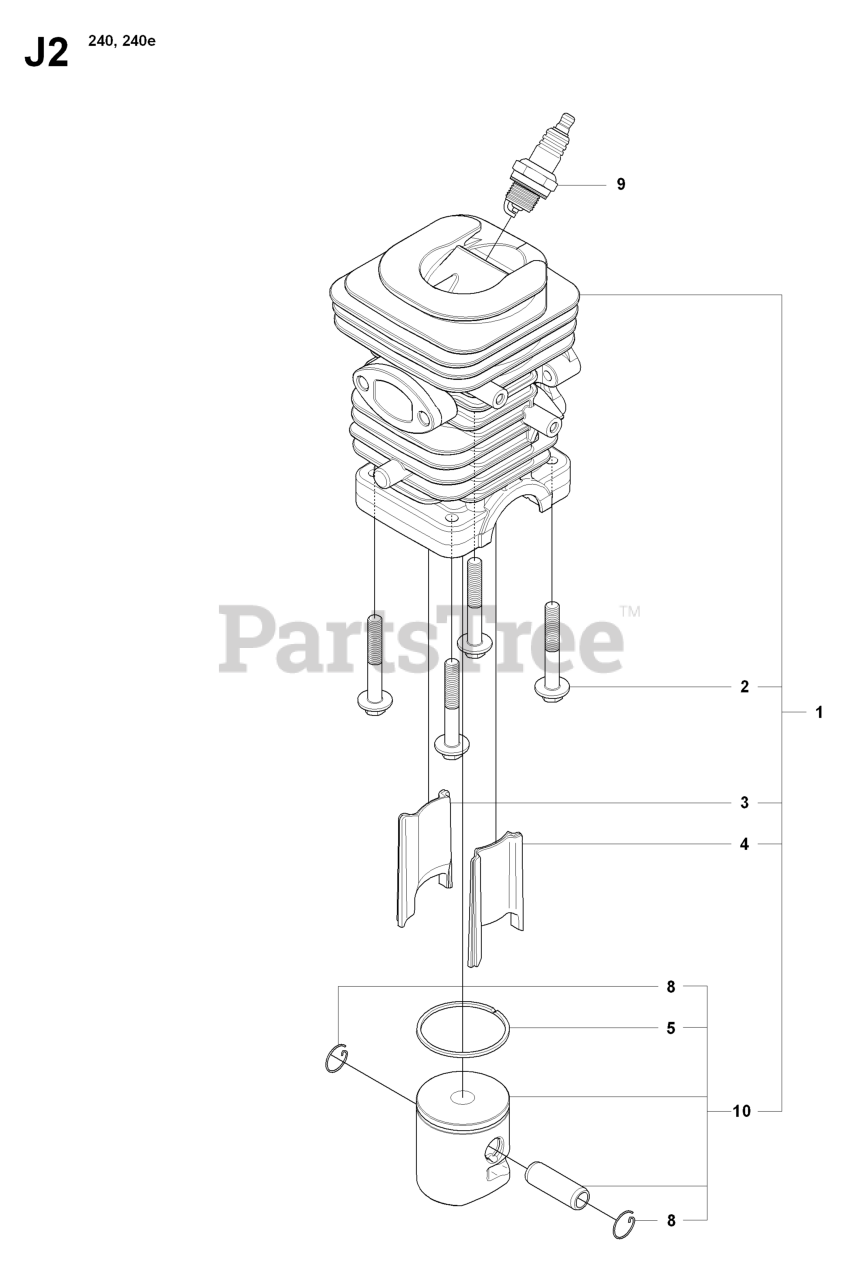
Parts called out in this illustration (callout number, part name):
1	%KIT, CYLINDER & PISTON
3	INSERT TRANSFER LEFT
4	INSERT TRANSFER RIGHT
5	PISTON RING
8	C-CLIP,PSTN PIN 36/41
9	SPARK PLUG RCJ7Y
10	PISTON KIT
